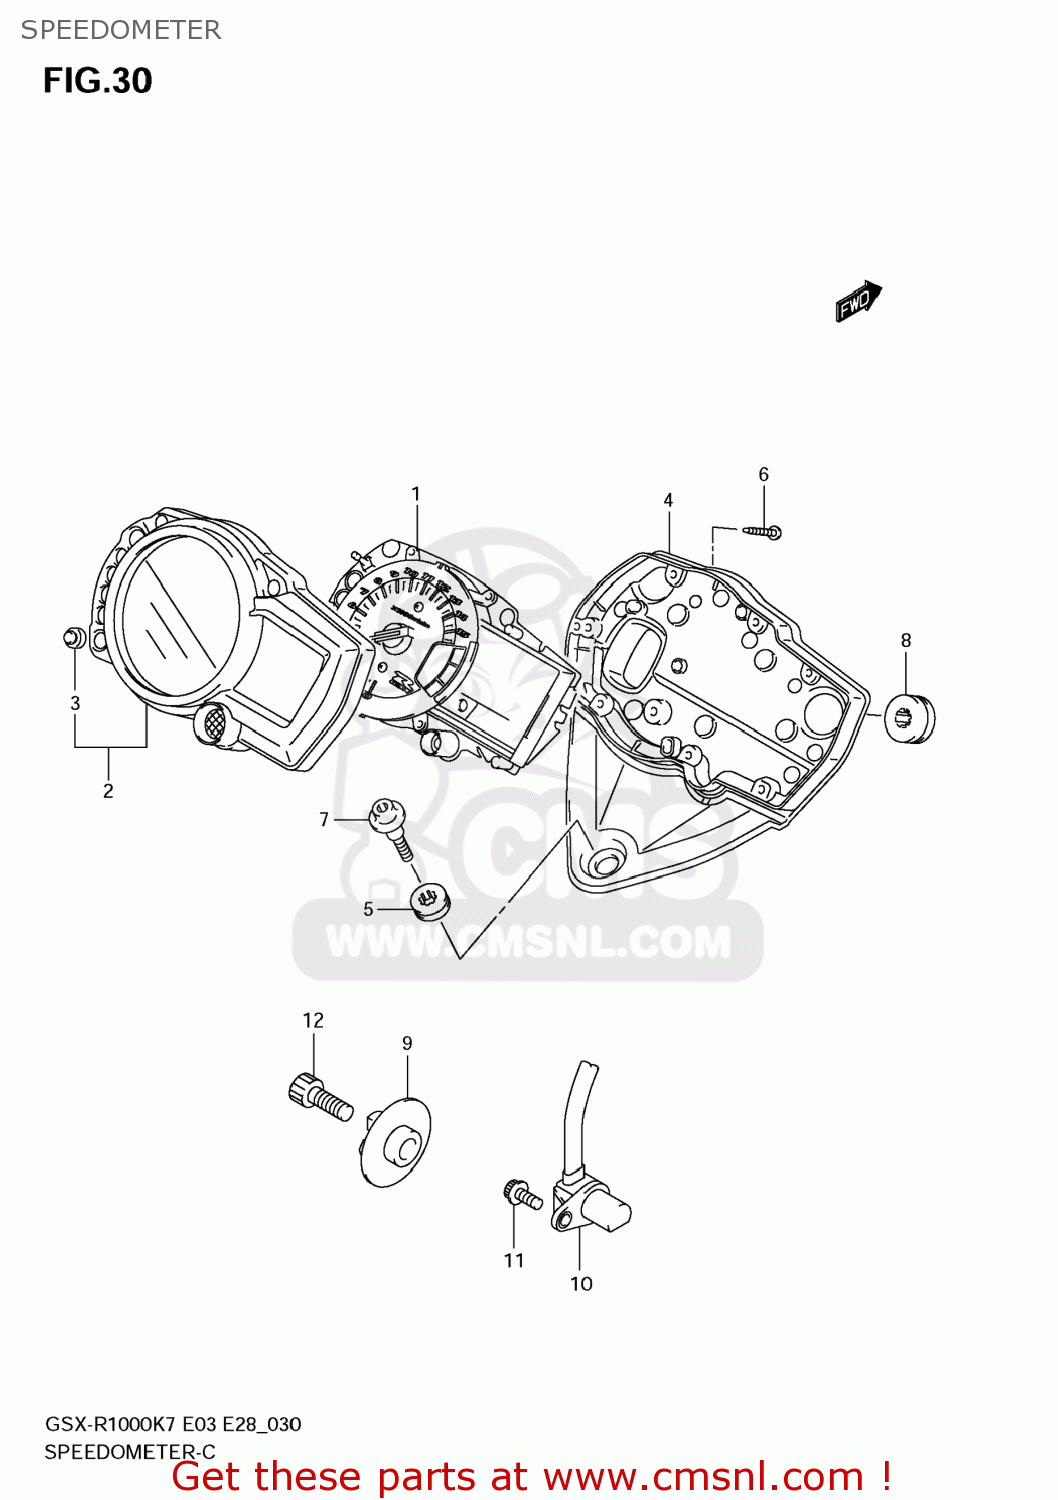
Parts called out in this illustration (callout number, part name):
1	SPEED & TACHOMETER ASSY
2	UPR CASE
3	RUBBER,SWITCH
4	LWR CASE
5	CUSHION,METER
6	SCREW(3X16)
7	SCREW,SPEEDOMETER
8	CUSHION
9	ROTOR,SPEED
10	SENSOR,SPEED
11	BOLT(5X16)
12	BOLT
